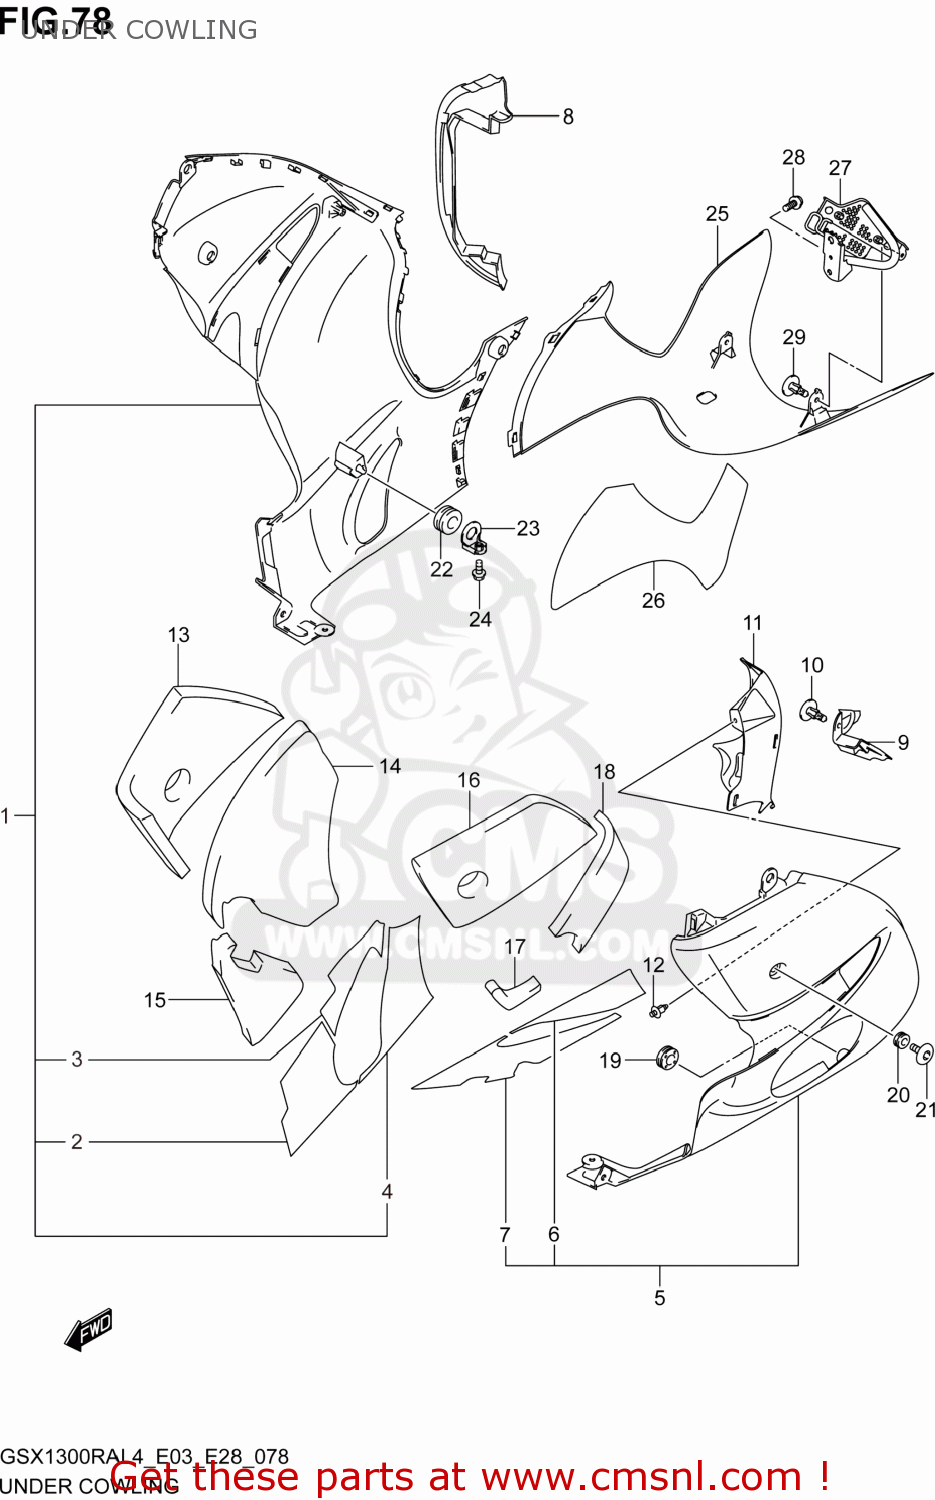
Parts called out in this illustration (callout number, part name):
1	COWLING,UNDER,R(RED)
2	SHIELD,UNDER COWL HEAT,R NO.1
3	SHIELD,UNDER COWL HEAT,R NO.3
4	SHIELD,UNDER COWL HEAT,R NO.2
5	COWLING,UNDER,L(RED)
6	SHIELD,UNDER COWL HEAT,L NO.1
7	SHIELD,UNDER COWL HEAT,L NO.2
8	PROTECTOR,COWLING UNDER,R
9	PROTECTOR,COWLING UNDER,L
10	CLIP
11	COVER,UNDER COWL,L
12	CLIP(BLACK)
13	CUSHION,UNDER COWLING,R NO.1
14	CUSHION,UNDER COWLING,R NO.2
15	CUSHION,UNDER COWLING,R NO.3
16	CUSHION,UNDER COWLING,L NO.1
17	CUSHION,UNDER COWLING,L NO.2
18	CUSHION,UNDER COWLING,L NO.3
19	CUSHION,UNDER COWLING,L
20	CUSHION
21	BOLT(6X20)
22	CUSHION
23	PLATE,UNDER COWL
24	BOLT
25	COWLING,UNDER REAR
26	SHIELD,UNDER COWL HEAT
27	BRACKET,RR UNDER COWLING
28	BOLT
29	CLIP
